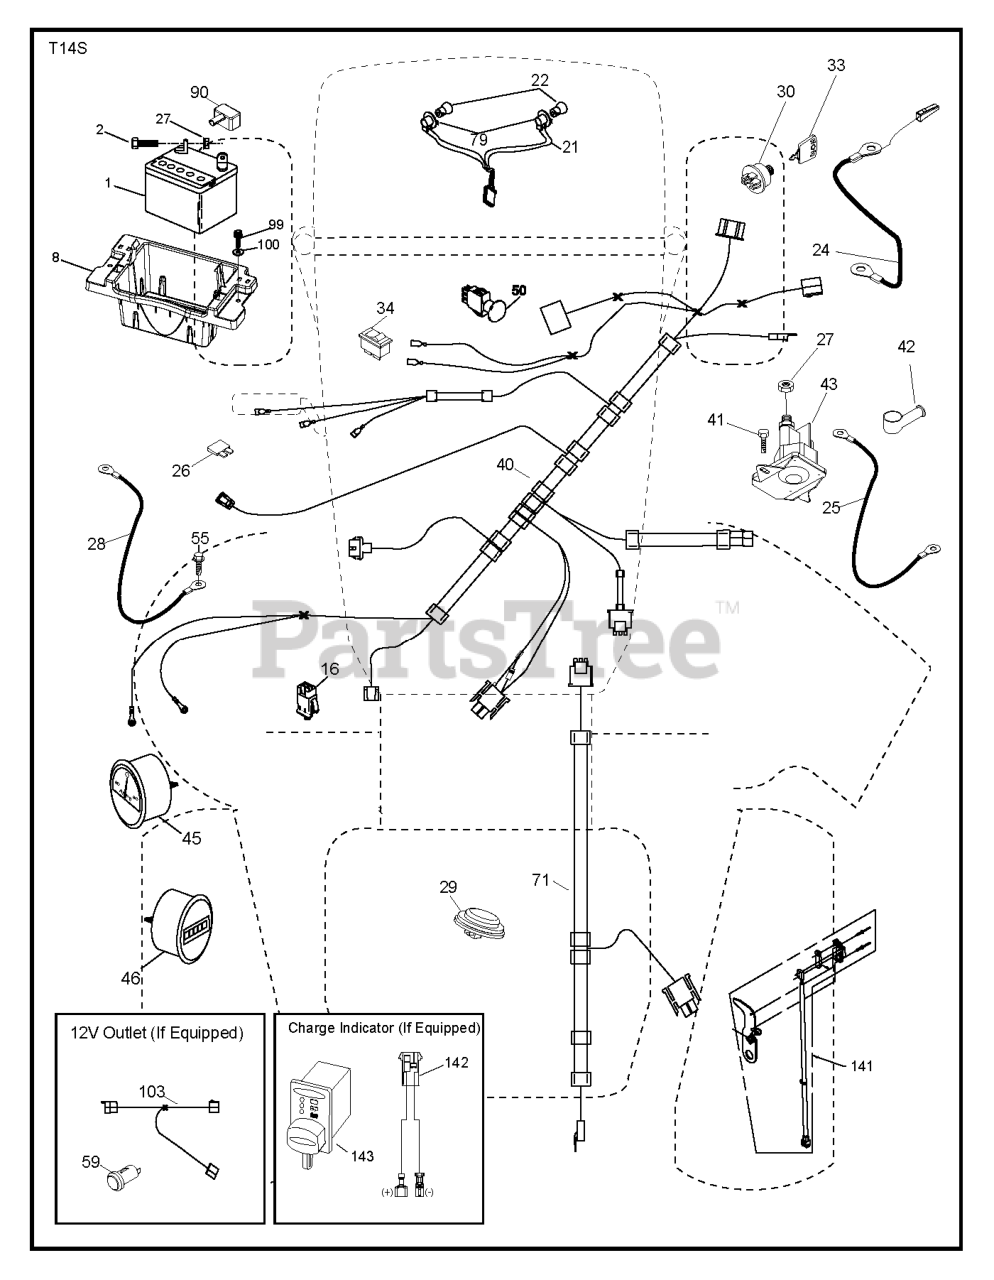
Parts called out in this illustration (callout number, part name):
1	Battery 12 Volt 25 Amp
2	BOLT.HEX.1/4.X.3/4.DICHROMATE
8	TRAY.BATTERY BOX.FRONT
16	SWITCH INTERLOOK PUSH-IN
21	HARNESS.LIGHT W/4152J BULBS
24	CABLE.FRBATT.W/WIRE.8GA.8
25	CABLE.STARTER.8GA.17.5
26	FUSE 20AMP
27	NUT
28	CABLE.GROUND.21"BLK.8GA.90T
29	SWITCH.SEAT.DELTA.OPC.
30	SWITCH.IGN.DELTA.W.LGH.ROS
33	KEY.CHAIN.BLISTER.PACK.GEN.USA
40	HARNESS.IGN.DASH.W/112V.PORT
41	SCREW
42	TERMINAL COVER
43	SOLENOID.W/BRASS.PLUNGER
45	GAUGE.AMMETER.SILVER/WHITE
46	GAUGE.HOUR.METER.SILVER/WHITE
50	RP.PTO.SWITCH.8 TERMINAL.BLACK
55	SCREW 5/16"
59	OUTLET.12-VOLT
71	HARNESS-CHASSIS SUB
79	BULB HOLDER ASM.
90	COVER.TERMINAL.BATTERY
99	SCREW HEXWSHR 1/4-20X3/4
100	WASHER
103	HARNESS.PIGTAIL.12V.OUTLET.
141	KIT.G700/G730.ROS 71750
142	RP HARNESS.JUMPER.CTEK
